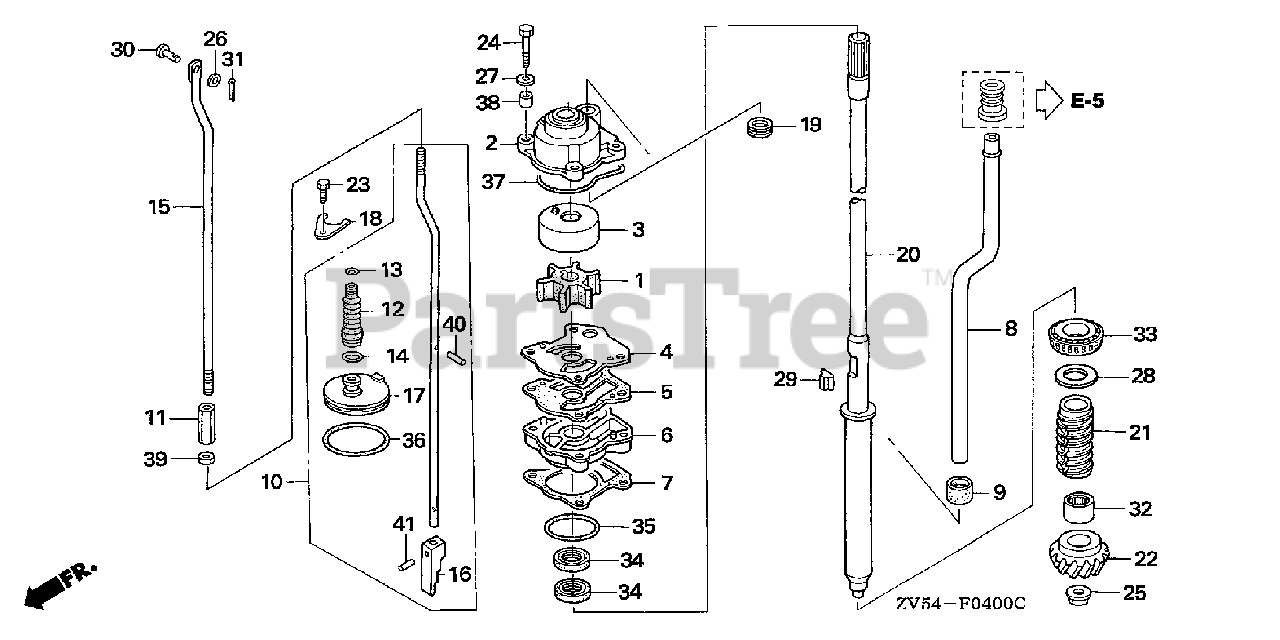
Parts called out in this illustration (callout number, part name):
1	IMPELLER, PUMP
2	HOUSING, IMPELLER
3	LINER, PUMP
4	COVER, IMPELLER
5	GASKET B, IMPELLER
6	HOUSING, WATER PUMP
7	GASKET, WATER PUMP
8	TUBE, WATER
9	RING, WATER TUBE SEAL
10	ROD, SHIFT (UL)
11	JOINT, SHIFT ROD
12	GROMMET, SHIFT ROD
13	BAND A, GROMMET
14	BAND B, GROMMET
15	ROD A, SHIFT
16	ROD, PUSH
17	HOLDER, SEAL
18	PLATE, SEAL HOLDER SETTING
19	GROMMET, EXTENSION CASE
20	SHAFT, VERTICAL
21	SLINGER, OIL
22	GEAR, PINION
23	BOLT, HEX. (6X12)
24	BOLT, HEX. (6X40)
25	NUT, SPECIAL FLANGE (12MM)
26	WASHER, PLAIN (5MM)
27	WASHER (6MM)
28	SHIM, GEAR (40X46X0.10) (A)
28	SHIM, GEAR (40X46X0.15) (B)
28	SHIM, GEAR (40X46X0.30) (C)
28	SHIM, GEAR (40X46X0.50) (D)
29	KEY, WOODRUFF
30	PIN (5X17)
31	PIN, COTTER (1.6MM)
32	BEARING, NEEDLE (7/8X11/8X1)
33	BEARING (25X47X15)
34	SEAL, WATER (17X30X7)
35	O-RING (41.7X3.5)
36	O-RING (47X3.1)
37	O-RING, WATER PUMP
38	COLLAR, IMPELLER HOUSING
39	NUT, HEX. (8MM)
40	PIN, SPRING (2X12)
41	ROLLER (3X14.8)
